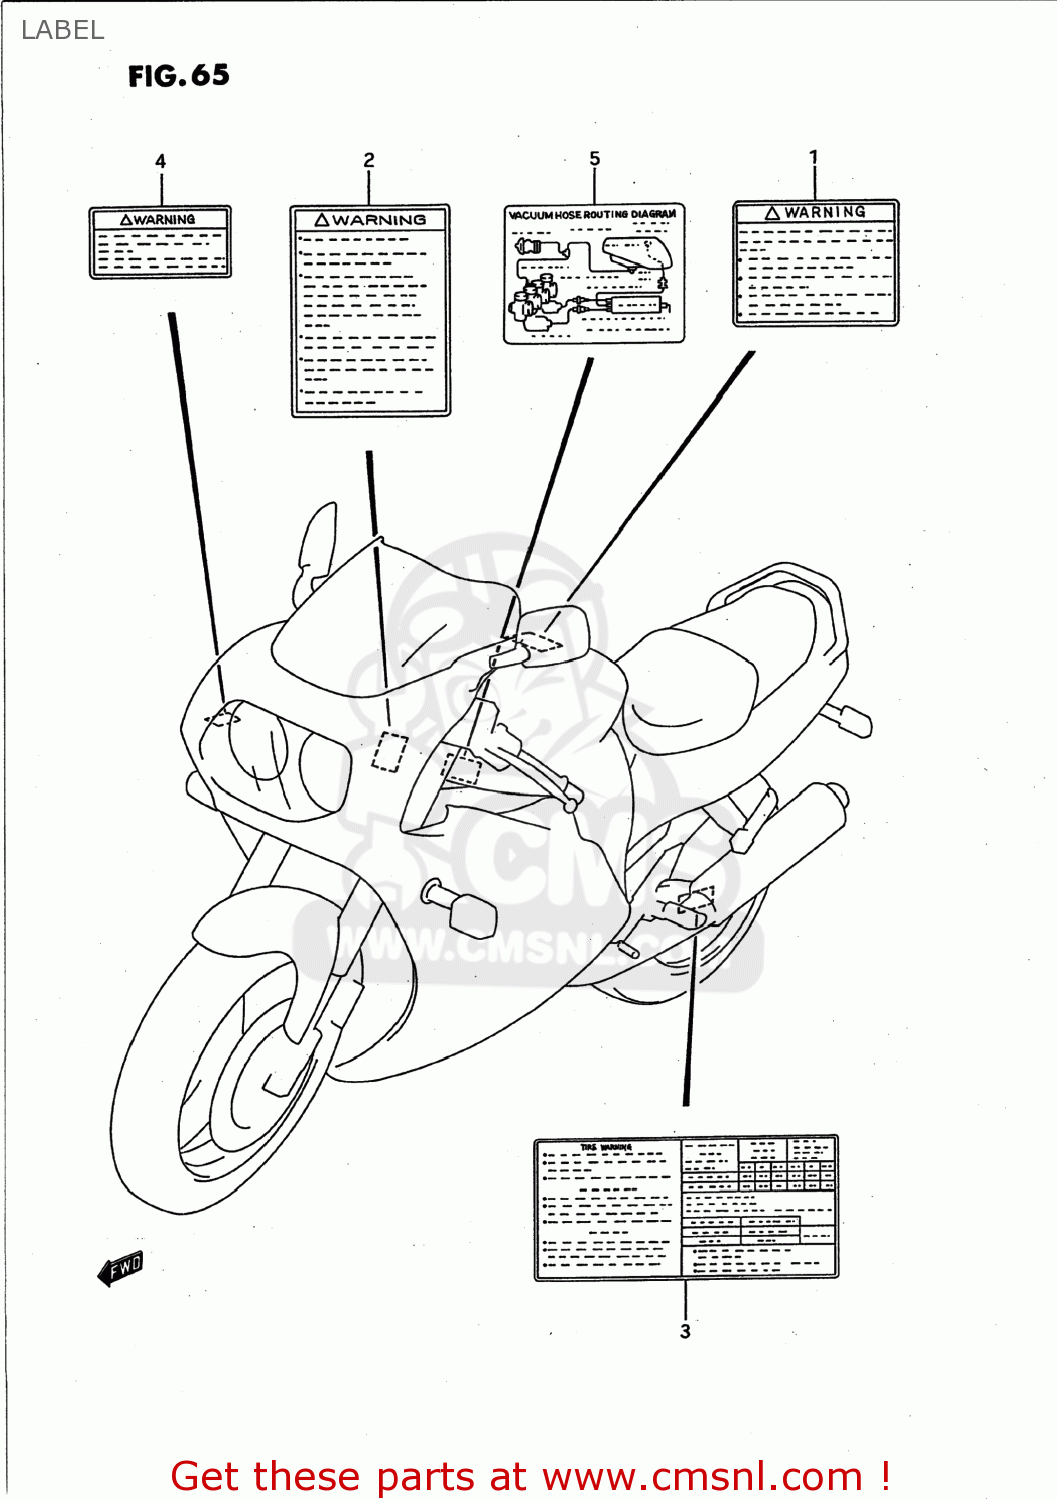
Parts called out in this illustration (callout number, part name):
1	LABEL
2	LABEL (WARNING SCREEN)
3	LABEL (TIRE INFORMATION)
4	LABEL,WARNING STEERING
5	LABEL (VACUUM HOSE ROUTING)
